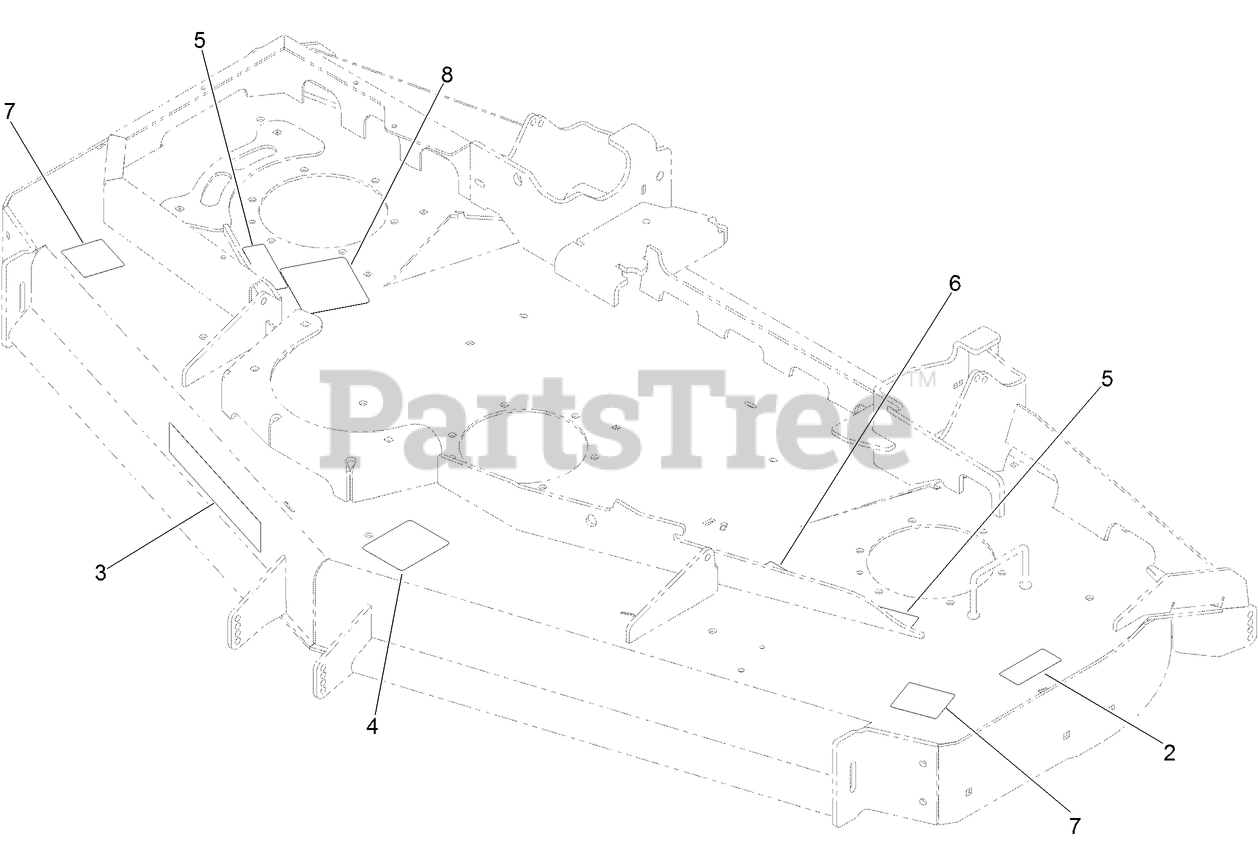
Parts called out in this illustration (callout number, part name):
2	DECAL-BOLT TORQUE
4	DECAL-ROLLER, ANTI-SCALP
5	DECAL-COVER, MISSING
6	DECAL-BELT ROUTING REAR
7	DECAL-DANGER, THROWN OBJECT
8	DECAL-SPINDLE CR, CE
